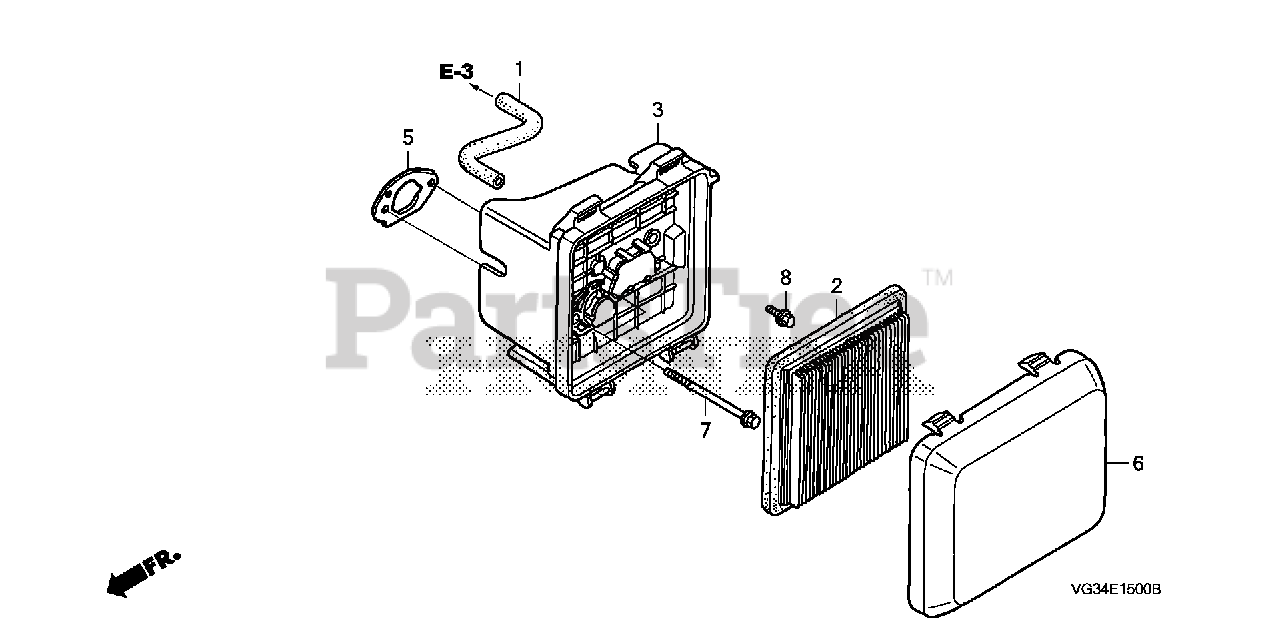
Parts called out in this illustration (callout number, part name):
1	TUBE, BREATHER
2	ELEMENT, AIR CLEANER
2	ELEMENT, AIR CLEANER (TOYO ROKI)
3	CASE ASSY., AIR CLEANER
5	GASKET, AIR CLEANER
6	COVER, AIR CLEANER
7	BOLT, FLANGE (6X86) (CT200)
8	BOLT, FLANGE (6X14)
